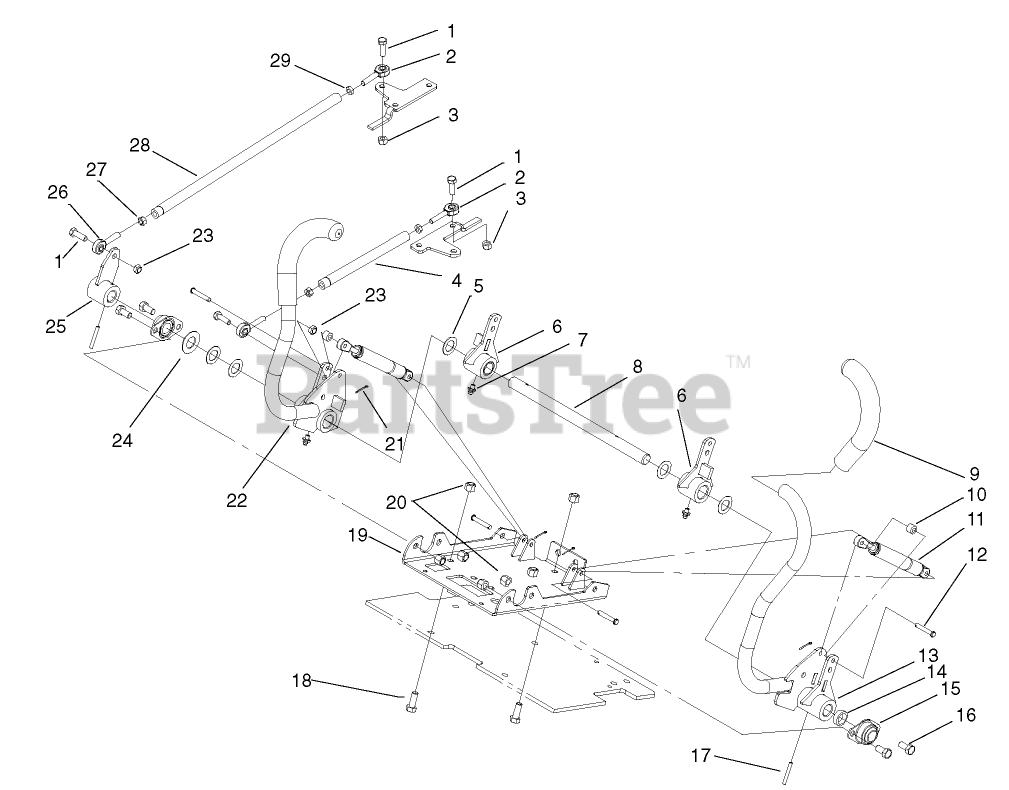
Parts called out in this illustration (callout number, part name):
1	SCREW-HH
2	BEARING-ROD END, RH
3	NUT-LOCK, NI
4	ROD-CONTROL, RH
5	WASHER-FLAT
6	CENTER CONTROL ASM
7	FITTING-GREASE
8	SHAFT-CONTROL
9	GRIP-CUSHION
10	SPACER - DAMPER
11	Damper-Control
12	PIN-CLEVIS
13	LH CONTROL HANDLE ASM
14	SPACER-CONTROL
15	BEARING
16	SCREW-HH
17	PIN-SPRING
18	SCREW-HH
19	CHANNEL MOUNT ASM
20	NUT-LOCK, NI
21	PIN-COTTER
22	RH CONTROL HANDLE ASM
23	NUT-LOCK, NI
24	WASHER-FLAT
25	CONTROL HUB ASM
26	BEARING-ROD END, LH
27	NUT-JAM
28	ROD-CONTROL, LH
29	NUT-JAM
